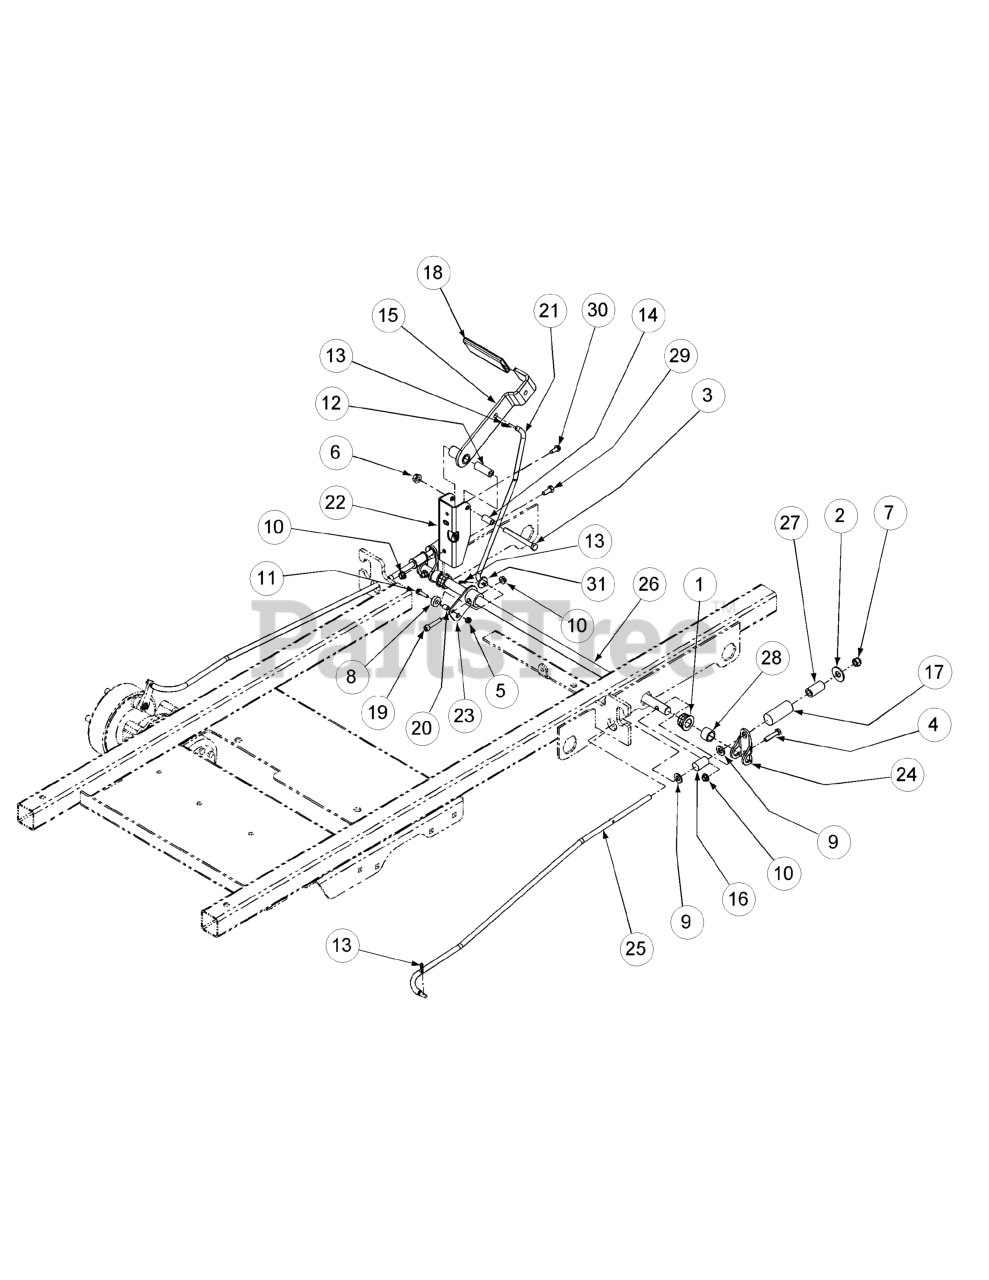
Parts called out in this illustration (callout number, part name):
1	Hex Flange Bearing, .752 ID
2	Flat Washer, 1/2
3	Hex Cap Screw, 3/8-16 x 3-1/4
4	Hex Cap Screw, 5/16-18 x 1-1/2
5	LockNut, 1/4-20, Nylon Insert
6	Flange Lock Hex Nut, 3/8-16
7	Nylock Nut, 7/16-14
8	Spacer, Control Rod
9	Washer, .469 ID x .875 OD x .105
10	HEX FLANGE NUT
11	Self Tapping Screw, 1/4-20 x 1.00
12	Spacer, .39 x .63 x 1.75
13	Cotter Pin, .072 x 1.12 Lg
14	Spacer, .375 x .50 x .75 Lg
15	Brake Handle
16	Neutral Brake Spring
17	Force Brake Spring
18	Parking Brake Grip
19	Socket Head Capscrew, 5/16-18 x 1.50
20	Spacer, .375 OD x .257 ID x .438
21	Brake Rod
22	PARK BRAKE BRACKET
23	Brake Arm Assembly
24	Brake Bracket
25	Linkage Brake Rod
26	Pivot Brake Shaft
27	Low Pressure Hose
28	Spacer, .76 ID x 1.0 OD x .75
29	HHCS, 5/16-18 x 1.0
30	Screw, TT, 1/4-20, 0.75, Hex Index Washer
31	Flat Washer, .406 ID, 1.0 OD, .105
